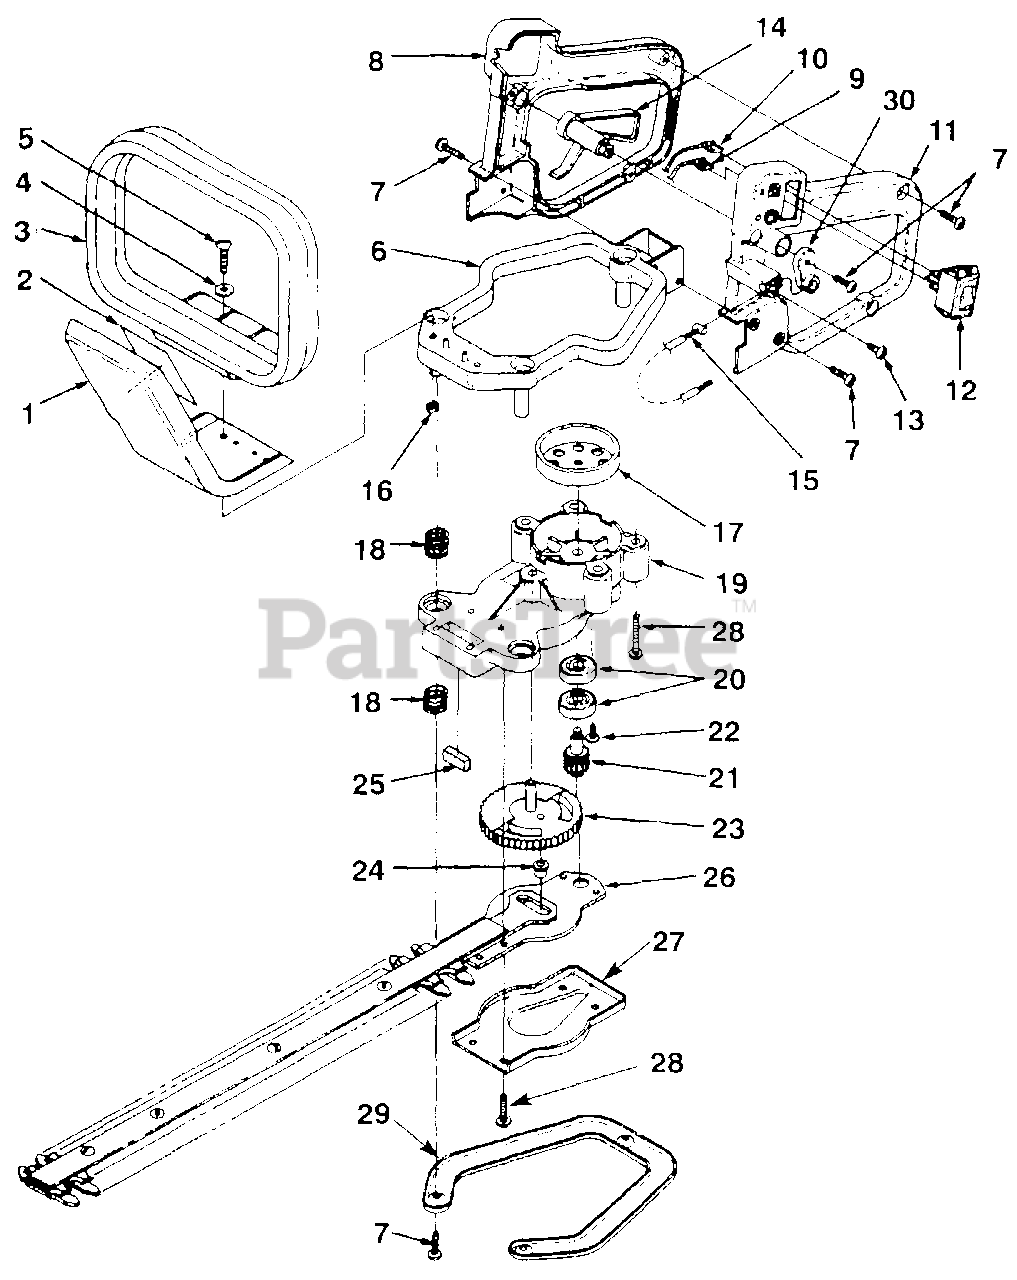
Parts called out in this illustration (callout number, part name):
1	GUARD-Hand (HX16, HT17, HT19)
2	DECAL-Caution
2	DECAL -Warning (HT17I, HT19I, HT21I)
3	HANDLE-Front
4	WASHER-Flat (10-24)
5	SCREW-Thread Form. (10-24 X 3/4")
6	BASE-Vibration Isolator
7	SCREW-Thread Form. (#8 X 3/4")
8	HANDLE-Rear (Right)
9	LEAD-Electrical
10	LEAD-Ground
11	HANDLE-Rear (Left)
12	SWITCH
13	SCREW-Thread Form. (#10 X 1/2")
14	TRIGGER
15	CABLE-Throttle
16	NUT-Hex (10-24)
17	DRUM-Clutch
18	SPRING-Compression
19	GEAR BOX ASSEMBLY
20	BEARING-Ball
21	PINION & SCREW ASSEMBLY
22	SCREW-Thread Form. (#10 X 1/2")
23	GEAR & PIN ASSEMBLY
24	BUSHING
25	BLADE-Seal
26	BLADE ASSY. (HX16, HT17, HT17I)
27	COVER-Gear Box
28	SCREW-Thread Form. (#10 X 7/8")
30	LEVER-Trigger
